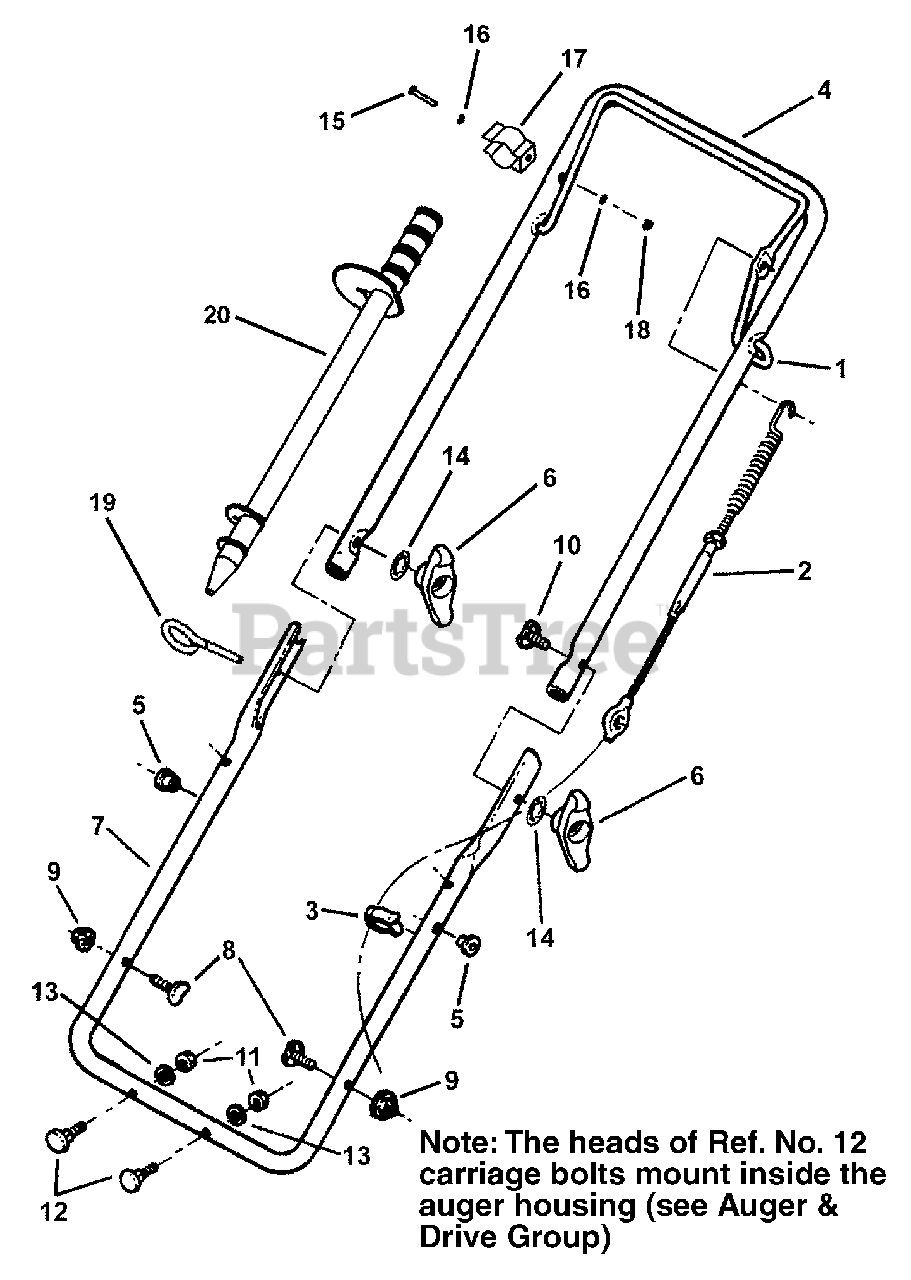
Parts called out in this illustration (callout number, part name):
1	BAIL, Drive Control
2	CABLE, Drive Control
3	CLIP, Wiring Harness
4	HANDLE, Upper
5	INSERT, Nylon
6	KNOB, 5/16-18 Wing, Black
7	HANDLE, Lower
8	BOLT, 5/16-18 x 1-3/8" Curved Head
9	NUT, 5/16-18 Hex Flange Lock, Grade 5
10	BOLT, 5/16-18 x 2" Curved Head, Grade 2
11	NUT, 5/16-18 Hex
12	CARRIAGE BOLT, 5/16-18 x 1-1/2, Grade 5
13	WASHER, 5/16 Split Lock
14	WASHER, 5/16 Internal Tooth Lock
15	SCREW, Hex Head Cap, #10-24 x 1-1/4, Grade 5
16	WASHER, #10 Flat
17	HOLDER, Clean-Out Tool, Upper
18	NUT, Hex Center Lock, #10-24
19	HOLDER, Clean-Out Tool, Lower, 5/16-18 thread
20	TOOL, Clean-Out
